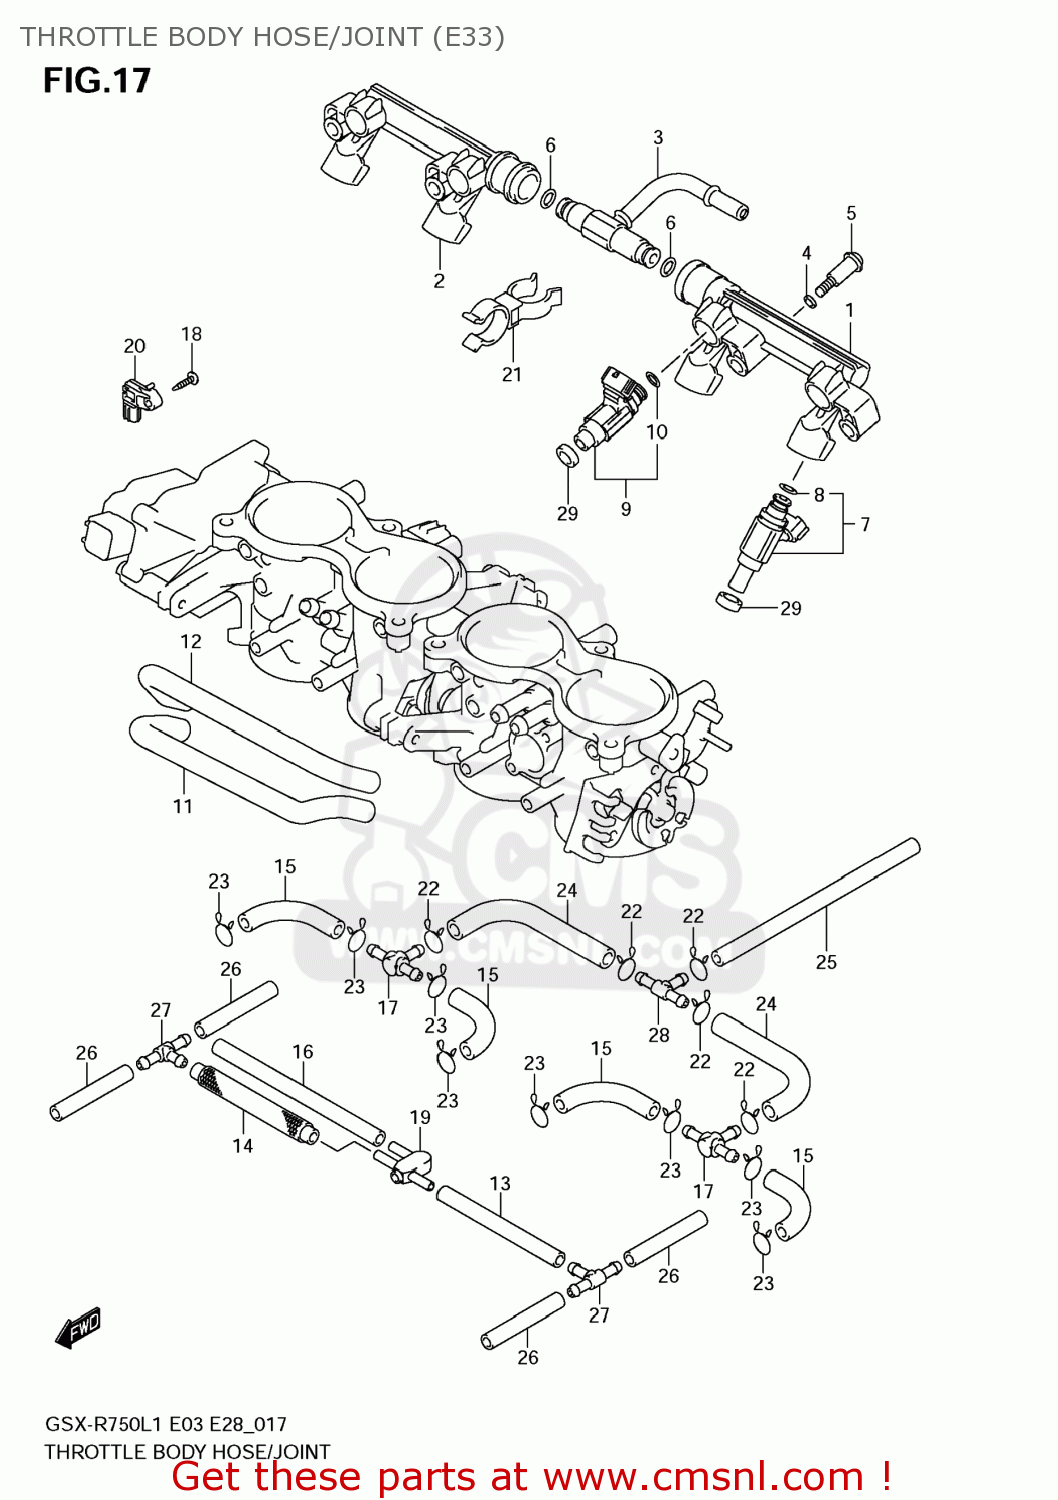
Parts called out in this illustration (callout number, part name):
1	DELIVERY PIPE
2	DELIVERY PIPE
3	NIPPLE ASSY
4	PACKING (NAS)
5	SCREW
6	O RING
7	INJECTOR ASSY
8	O-RING
9	INJECTOR ASSY
10	O-RING
11	HOSE
12	HOSE
13	HOSE
14	HOSE
15	HOSE(L:425)
16	HOSE
17	3WAY,VACUUM HOSE
18	SCREW
19	JOINT
20	SENSOR,BOOST
21	CLAMP
22	CLIP
23	CLIP
24	HOSE
25	HOSE
26	HOSE
27	NIPPLE
28	NIPPLE
29	SEAL
